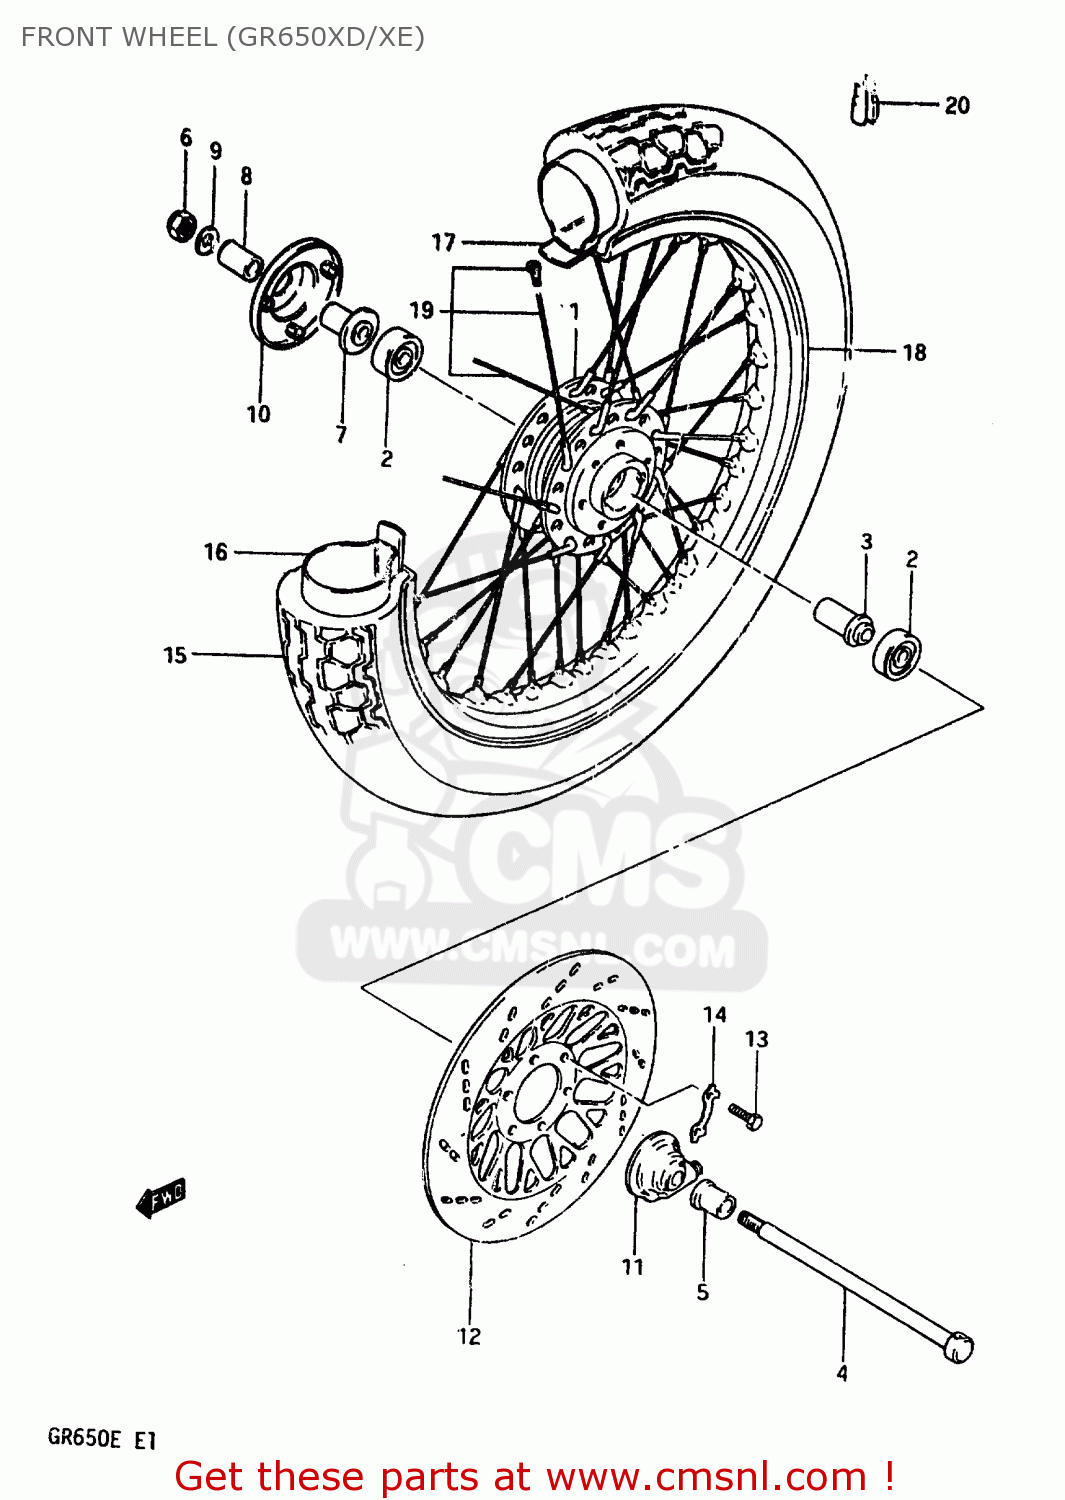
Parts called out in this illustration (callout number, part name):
1	DRUM,FRONT HUB
2	BEARING
3	SPACER,FR HUB BEARING
4	AXLE,FR
5	SPACER,FRONT AXLE,RIGHT
6	NUT
7	SPACER,FR AXLE,R
8	SPACER,FRONT AXLE,RIGHT
9	WASHER
10	COVER,FR HUB,R
11	BOX ASSY,SPEEDOMETER GEAR
12	DISC,FR BRAKE,L
13	BOLT(8X25)
14	WASHER
15	TIRE,FRONT
16	TUBE,INNER
17	PROTECTOR,WHL INR TUBE
18	RIM,FRONT WHEEL (1.85X19)
19	SPOKE SET,FRONT
20	BALANCER,WHEEL (B)
